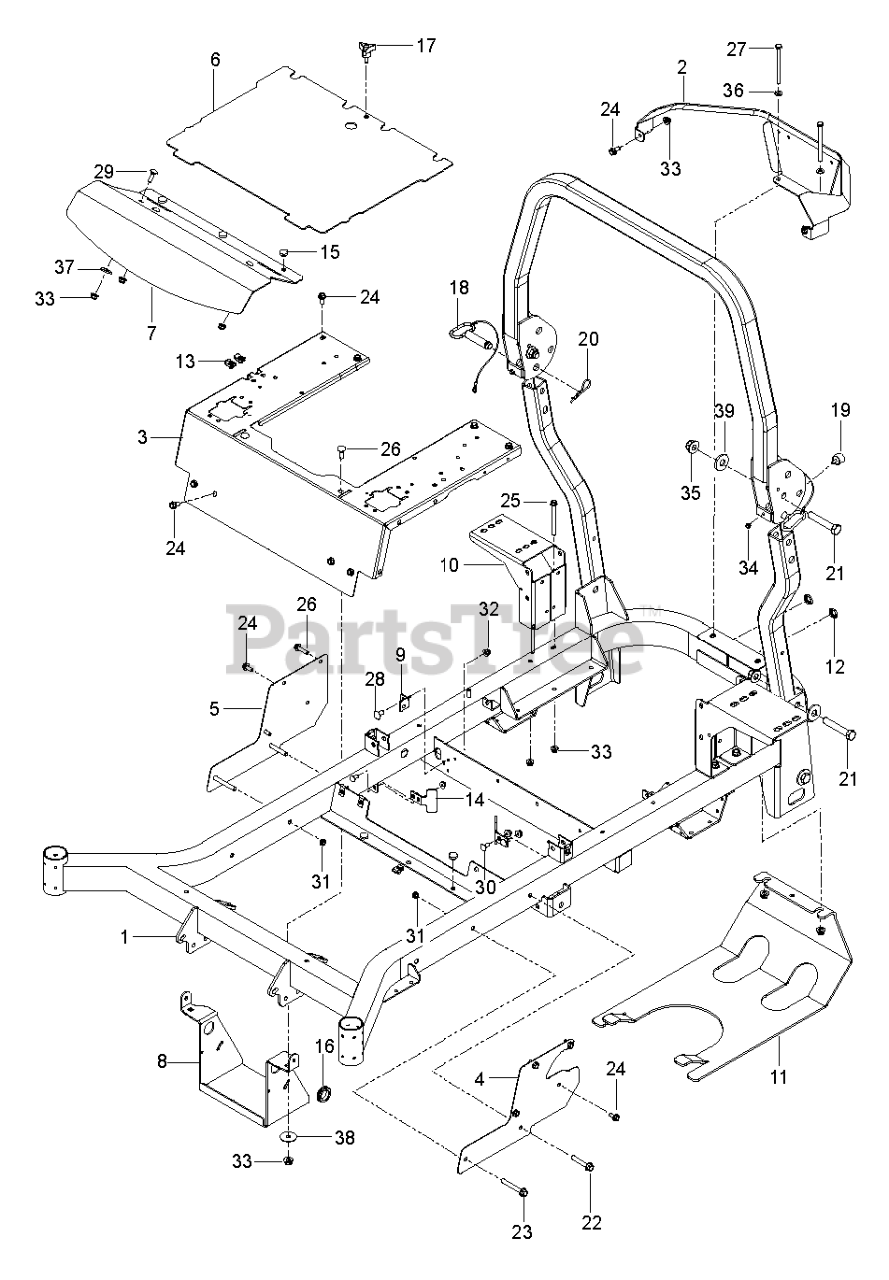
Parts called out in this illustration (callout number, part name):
1	KIT.FRAME.W/DECALS.X668
2	GUARD.PNT.REAR.MZ.GRAY
3	SUPPORT.PNT.SEAT.CONTROL.ORNG
4	BRACKET SIDE, LT ORANGE
5	BRACKET.PNT.SIDE.RT.JNX667
6	PLATE, FLOOR W/DECALS
7	PLATE, FOOTREST
8	BRACKET.PNT.BATTERY.BLK
9	BRACKET.DAMPENER.BLACK
10	MOUNT, TANK, ZT BLK
11	GUARD SKID PNT 498
12	CAP.PLUG.BP-1.BLACK
13	U-CLIP 5/16-18 NUT RETAINER
14	STOP, DECK, EZ+
15	GROMMET, BUMPER
16	RUBBER GROMMET
17	KNOB W/STUD
19	BUMPER, MALE STUD, 1/4-20
20	PIN HAIR .148 X 2-15/16 #210
21	5/8-11 X 3-1/2 HHB GRADE 5
22	HHFS 3/8-16 X 2.5 GR 5 ZD
23	HHFS 3/8-16 X 2-3/4 GR5 ZD
24	HHFS 5/16-18 X 3/4
25	BOLT.HEX.FLNG.5/16-18X3.75
26	HHFS 5/16-18 X 1.25 TPBLT GD 5
27	HCS 5/16C X 4
28	RHSNB 3/8-16 X 3/4 GR 5 BLK ZN
29	RHSNB 5/16C X 1
30	RP BOLT 5/16-18 X3/4 ZN/YEL GR
31	NUT HEX 3/8-16 NYLON, THIN
32	NUT 3/8-16 HEX FLG NYLOC ZD
33	5/16-18 NYLOC FLANGE NUT
34	NUT.1/4-20.HEX.NYLOC.ZD
35	NUT 5/8-11 FLG NYLOC ZD
37	WASHER 1/2" FLAT
38	WASHER.13/32X1-1/2X16GA
39	WASHER, 5/8 FLAT
